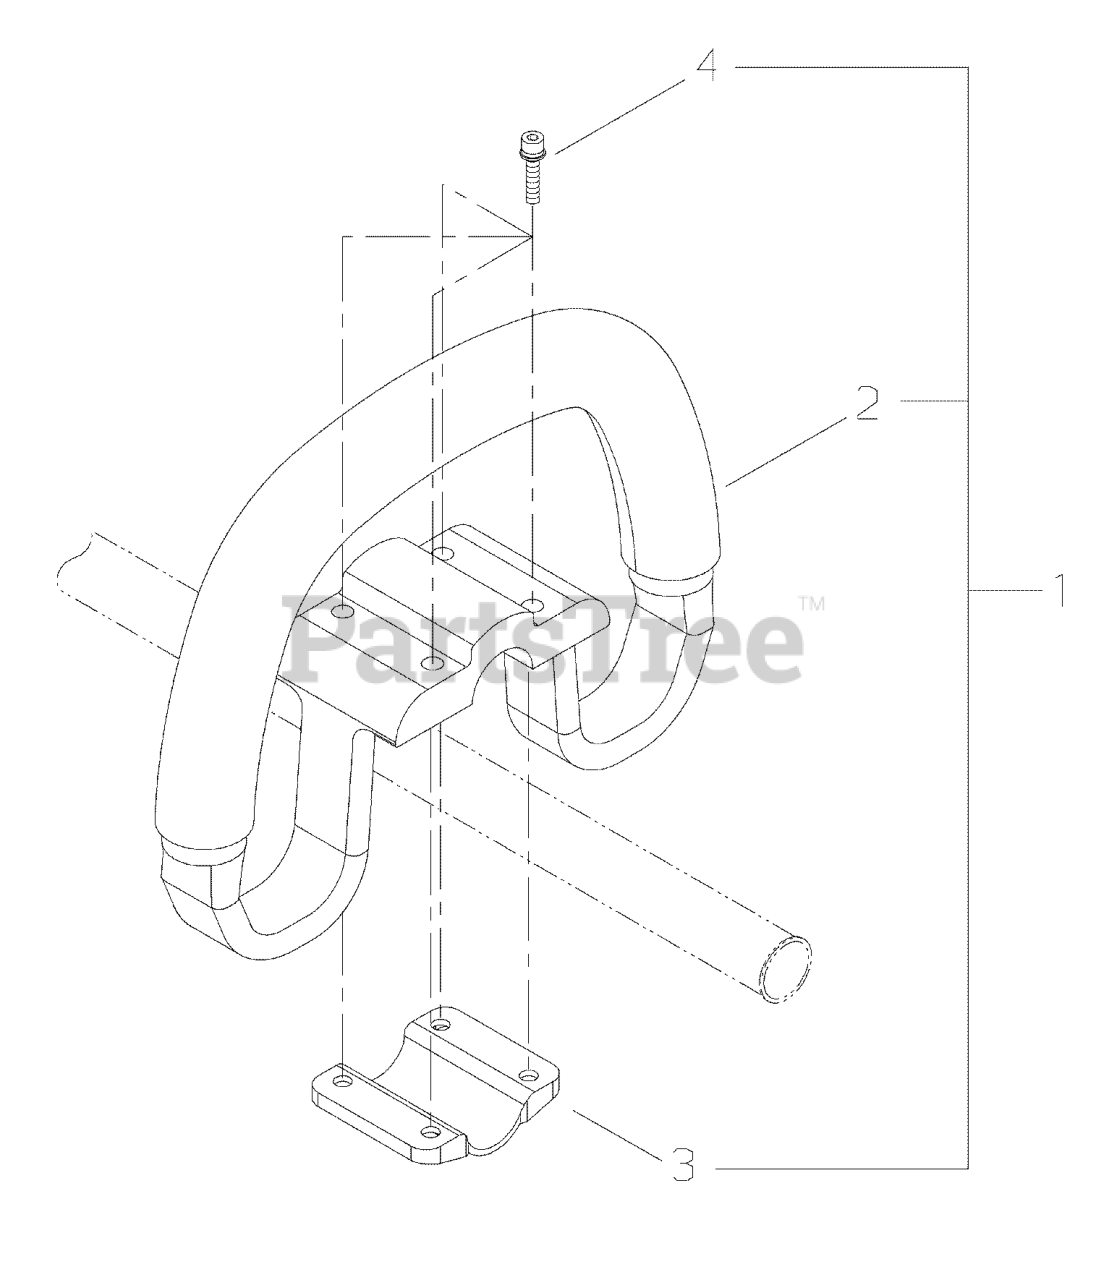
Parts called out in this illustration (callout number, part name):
1	HANDLE ASSY
2	HANDLE
3	CLAMP - LOWER
4	SCREW - 5X25
